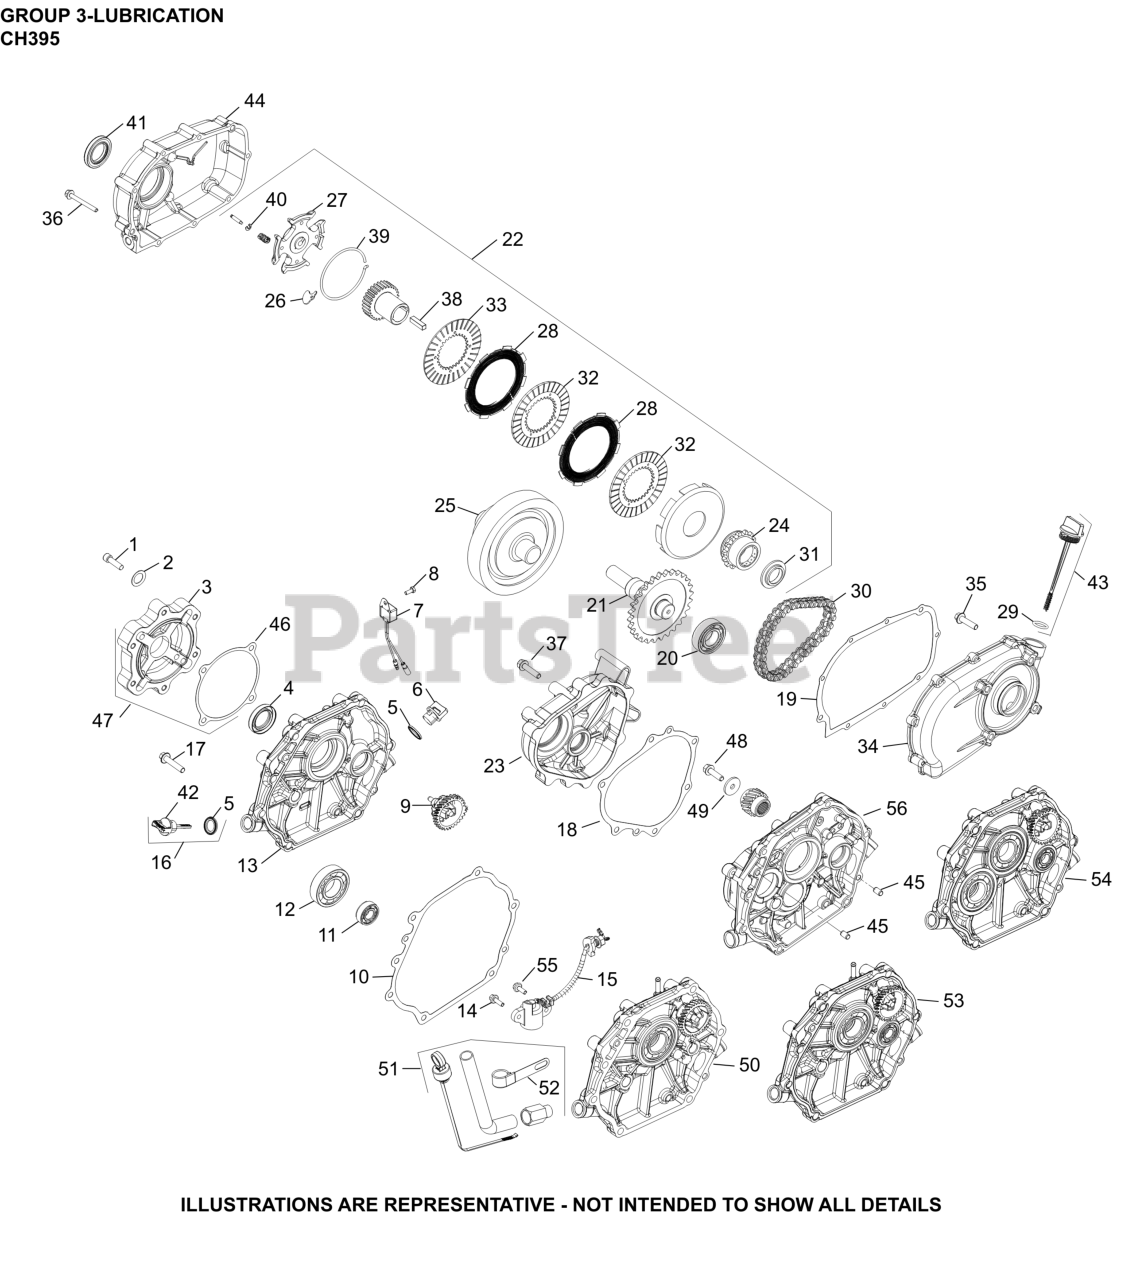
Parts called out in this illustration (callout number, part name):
4	SEAL, RADIAL SHAFT
5	SEAL, DIPSTICK
7	CONTROL, OIL ALERT UNIT
8	SCREW, HEX/PHILLIPS M5
9	GOVERNOR, ASSEMBLY
12	BEARING, CRANKSHAFT
14	SCREW, M6 X18
15	SWITCH, OIL SENSOR ASSEMBLY
16	DIPSTICK ASSEMBLY
17	SCREW, CLOSURE PLATE
42	DIPSTICK - USE 17 038 08-S
50	PLATE, CLOSURE & BEARING
55	SCREW, M6 X 16
